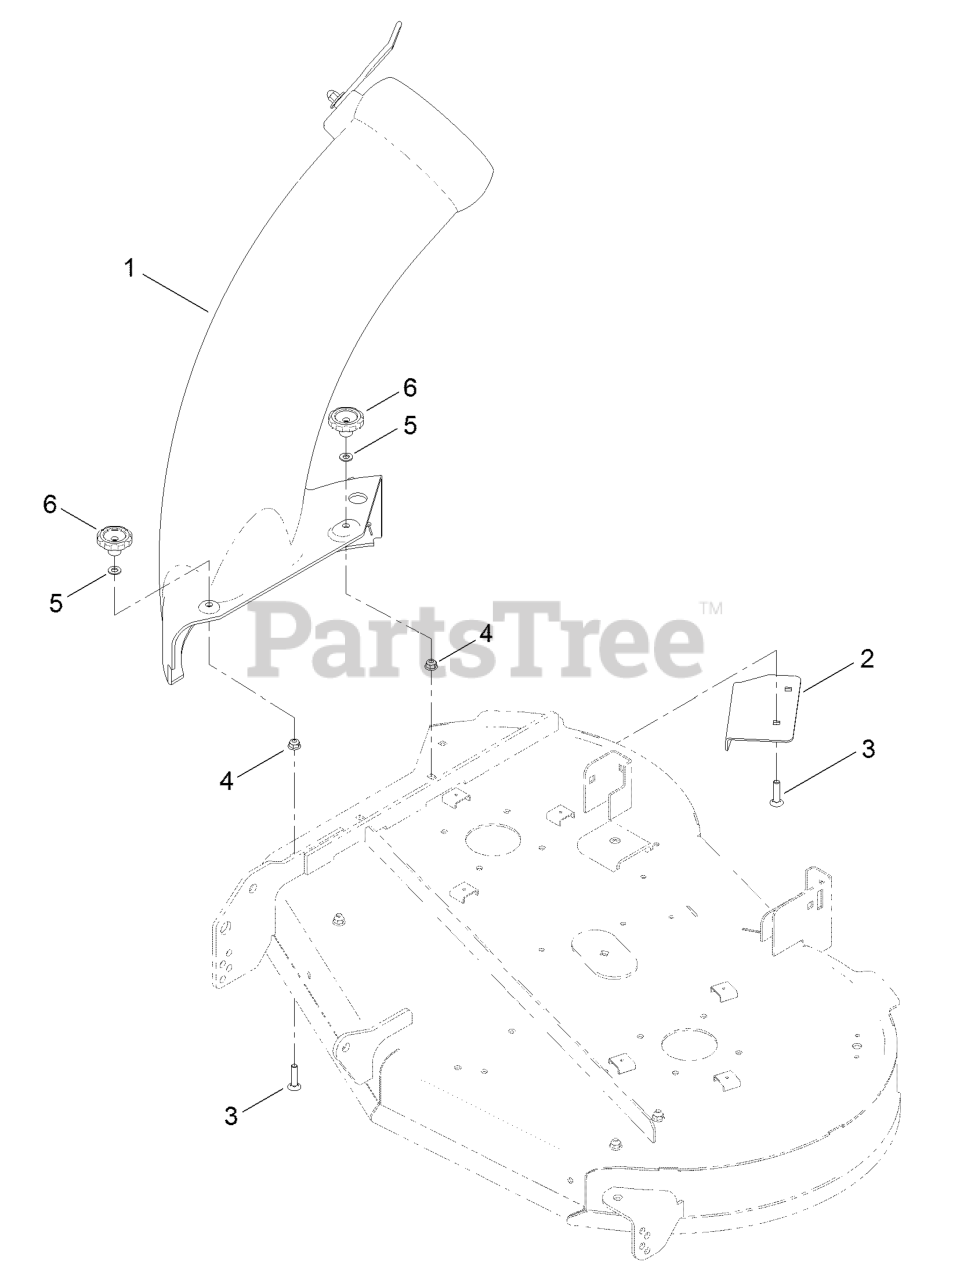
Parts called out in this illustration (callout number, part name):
1	CHUTE ASM
2	BAFFLE-CUTOFF
3	SCREW-CARR
4	NUT-HF, NI
5	WASHER-PLAIN
